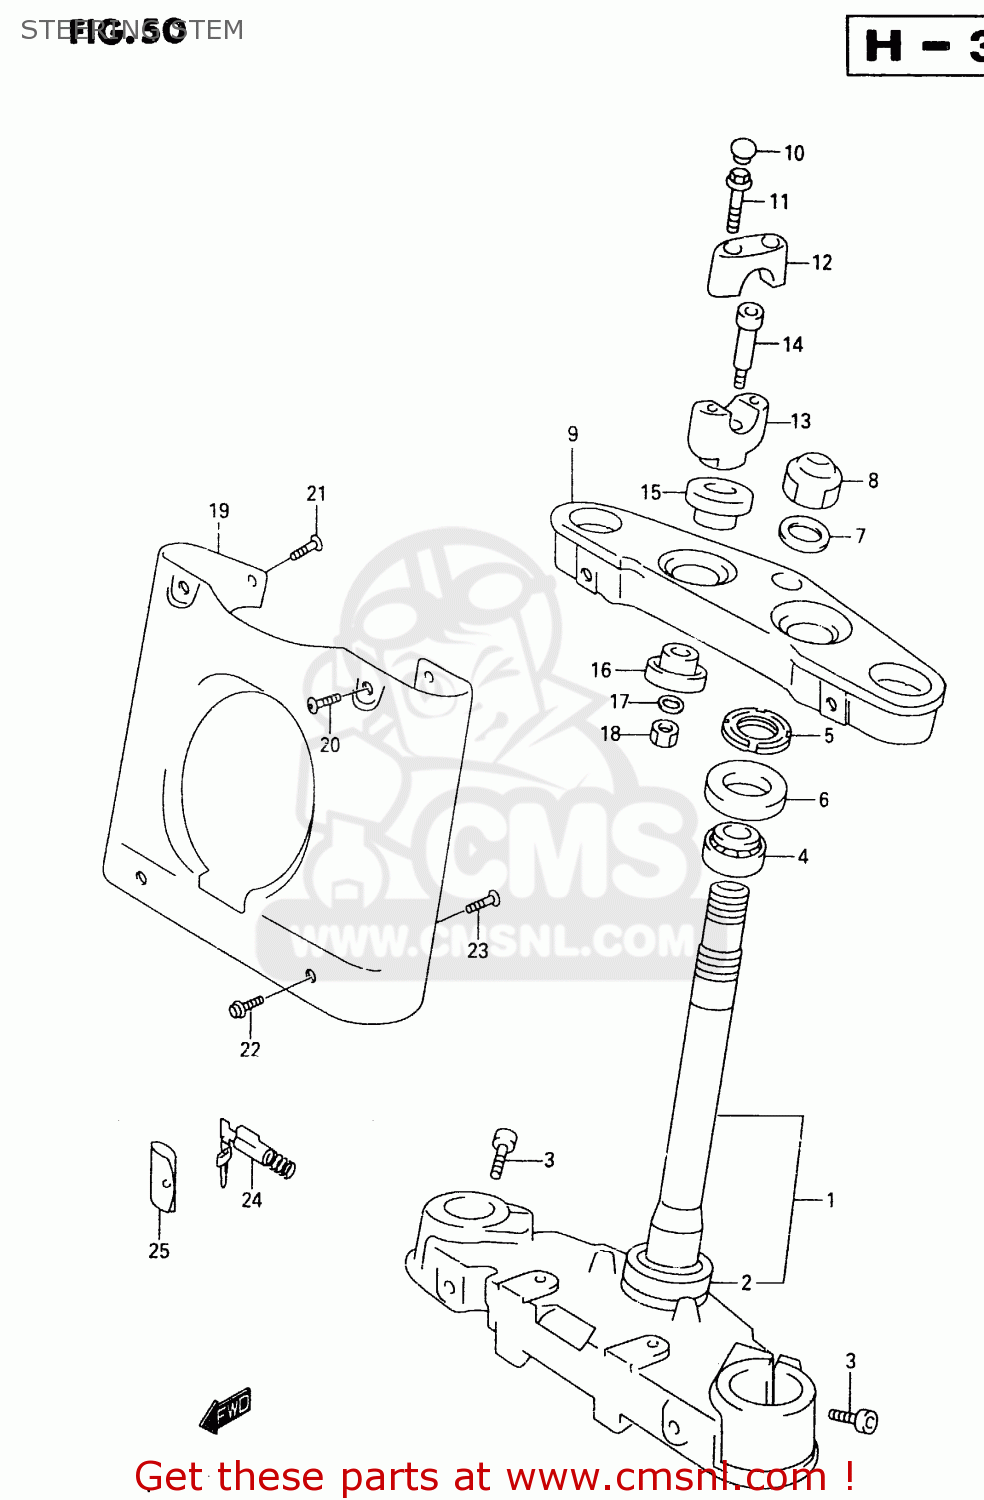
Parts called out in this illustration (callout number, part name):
1	STEM,STEERING
2	BEARING(30X55X17)
3	BOLT,STEM
4	BEARING(25X47X15)
5	NUT,STEERING STEM(25X44X10)
6	DUST SEAL,STEERING UPR
7	WASHER(22.5X32X1.6)
8	NUT,CAP
9	HEAD,STEERING STEM
10	CAP(OD:14.5)
11	BOLT
12	HOLDER,HANDLE UPR
13	HOLDER,HANDLE UNDER
14	BOLT
15	DAMPER,RUBBER
16	CUSHION,RUBBER UNDER
17	WASHER
18	NUT
19	COVER,FR FORK UPR
20	SCREW(8X16)
21	SCREW(6X12)
22	BOLT
23	SCREW(6X12)
24	LOCK SET,STEERING
25	CASE,STEERING KEY
